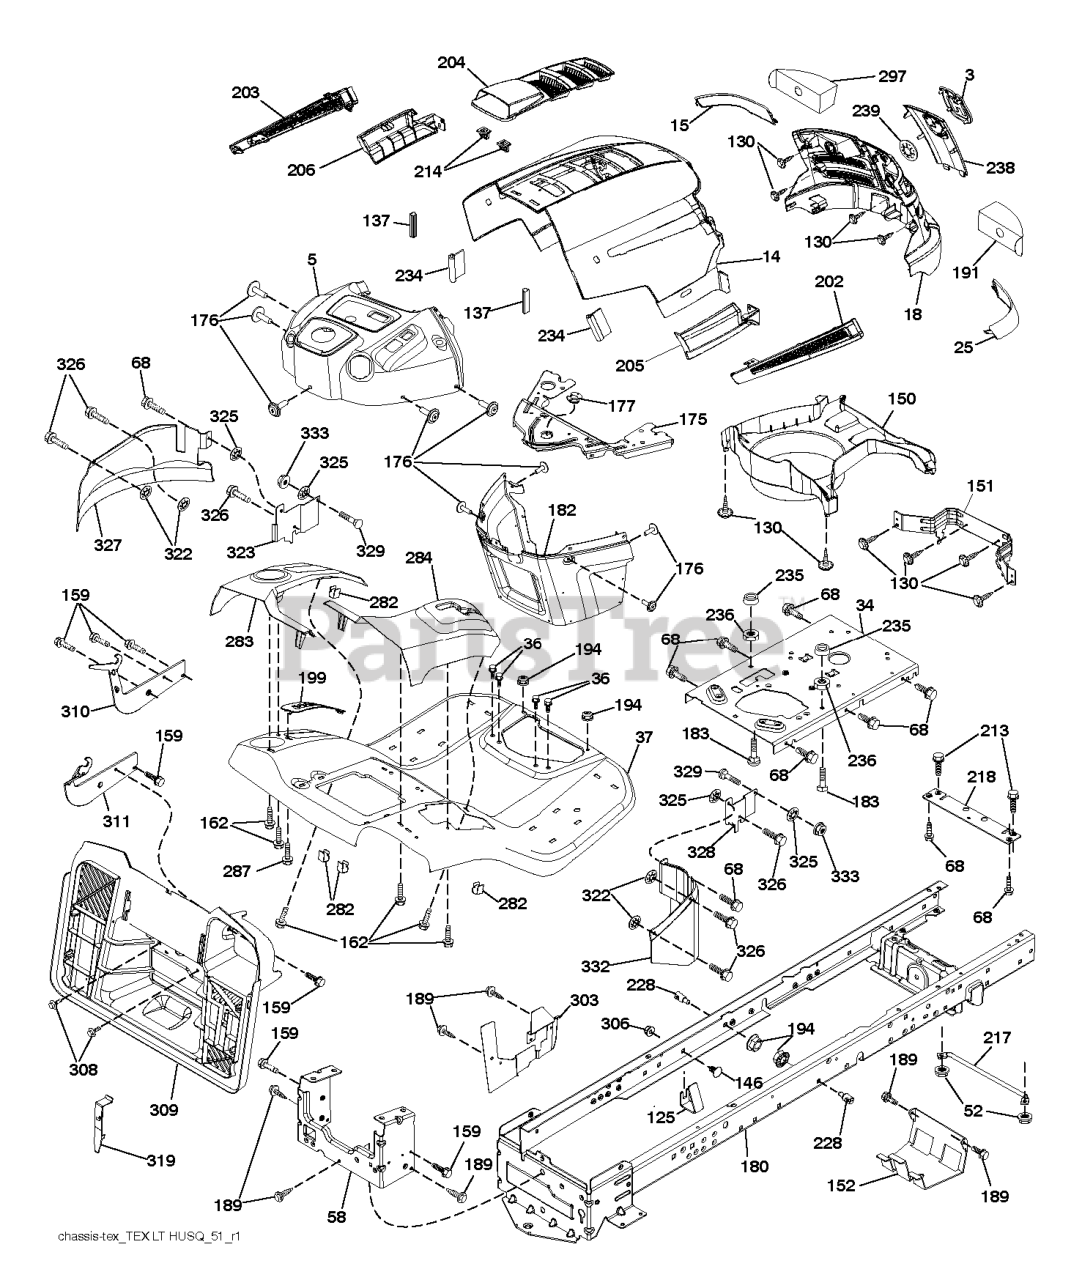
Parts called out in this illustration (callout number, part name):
3	LOGO.HUSQ.GT.LT.CROWN.H
5	SUBASM.DASH.UPPER.HLT.498
14	HOOD.HUSQVARNA.LT.ORANGE
15	LENS.HUSQVARNA LT.RH
18	GRILLE.SVC.HUSQVARNA.GREY
25	LENS.HUSQVARNA LT.RH
34	PLATE PLATE ENGINE
36	SCREW 5/16"
52	LOCKNUT
58	DRAWBAR UPPER 2PC SMALL FENDER
68	Screw 5/16-18 x 1/2 Hex, Self Tapping 5/16-18 x 1/2
125	CLIP.FUEL.LINE
130	SCREW.#10 X 0.750.BOS
137	BUMPER DASH
146	BOLT.RDHD.SHT.SQNK.3/8-16X5/8
151	BRACKET PIVOT
152	SHIELD.BROWNING.W/TEX
159	SCREW, 3/8-16X3/4
162	SCREW.HI-LO.CONSOLE
175	CROSSMEMBER
176	SCREW.#10-24X5/8.RN.QU
177	BUSHING STEERING
180	CHASSIS.WLDMNT.14GA.2PC.18".TI
182	DASH.LOWER.PREDATOR LT
183	BOLT.5/16-18X1-1/4 FULL THD
189	SCREW
191	INSERT.REFLECTIVE.RH.
194	NUT LOCK HEX FLANGE 5/16-18
199	PLATE DECK LIFT
202	VENT.SIDE.HUSQVARNA.LT.RT
203	VENT.SIDE.HUSQVARNA.LT.LFT
204	SUBASM.TOP.VENT.HUSQ.LT
205	SKIRT.SIDE.HUSQVARNA.LT.RT
206	SKIRT.SIDE.HUSQVARNA.LT.LEFT
213	BOLT
214	CLIP.RETAINER.TINNER.
217	ROD.PIVOT.HOOD
218	X-PIECE.HOOD.STOP.NON/
228	STUD.FASTNER.W/ANTI-ROTATE
234	BUMPER.HOOD.TEX.HUSQVARNA
235	SPACER FENDER
236	NUT.CENTERLOCK.5/16-
238	TRIM.HUSQ LT.668
282	CLIP.RETAINER.CONSOLE.LT.HUSQ
283	CONSL.DECKLIFT.LH.SRD.TEX.CRD
284	CONSL.SHFT.PEDAL.RH.SRD.TEXCRD
287	SCREW 1/4X20
297	INSERT REFLECTIVE
303	SHIELD CHASSIS LEFT
306	NUT LOCK FLG 3/8-16 UNC
308	BOLT.5/16-18UNCX3/4 W/SEMS.BLK
309	BACKPLATE.BAGGER.V2.SRD
310	LH.ADJUST.HANGER.BRACKET.ASM
311	RH.ADJUST.HANGER.BRACKET.ASM
319	BRACKET.ACTUATOR.BAGGER.SRD
322	PALNUT 1/4
323	GUARD FRONT LEFT
325	WASHER 5/16"
326	SCREW 14-20 X 5/8
327	GUARD LEFT
328	GUARD FRONT RIGHT
329	BOLT
332	GUARD RIGHT
333	NUT.71038.31-18.HEX.NYLOCK
